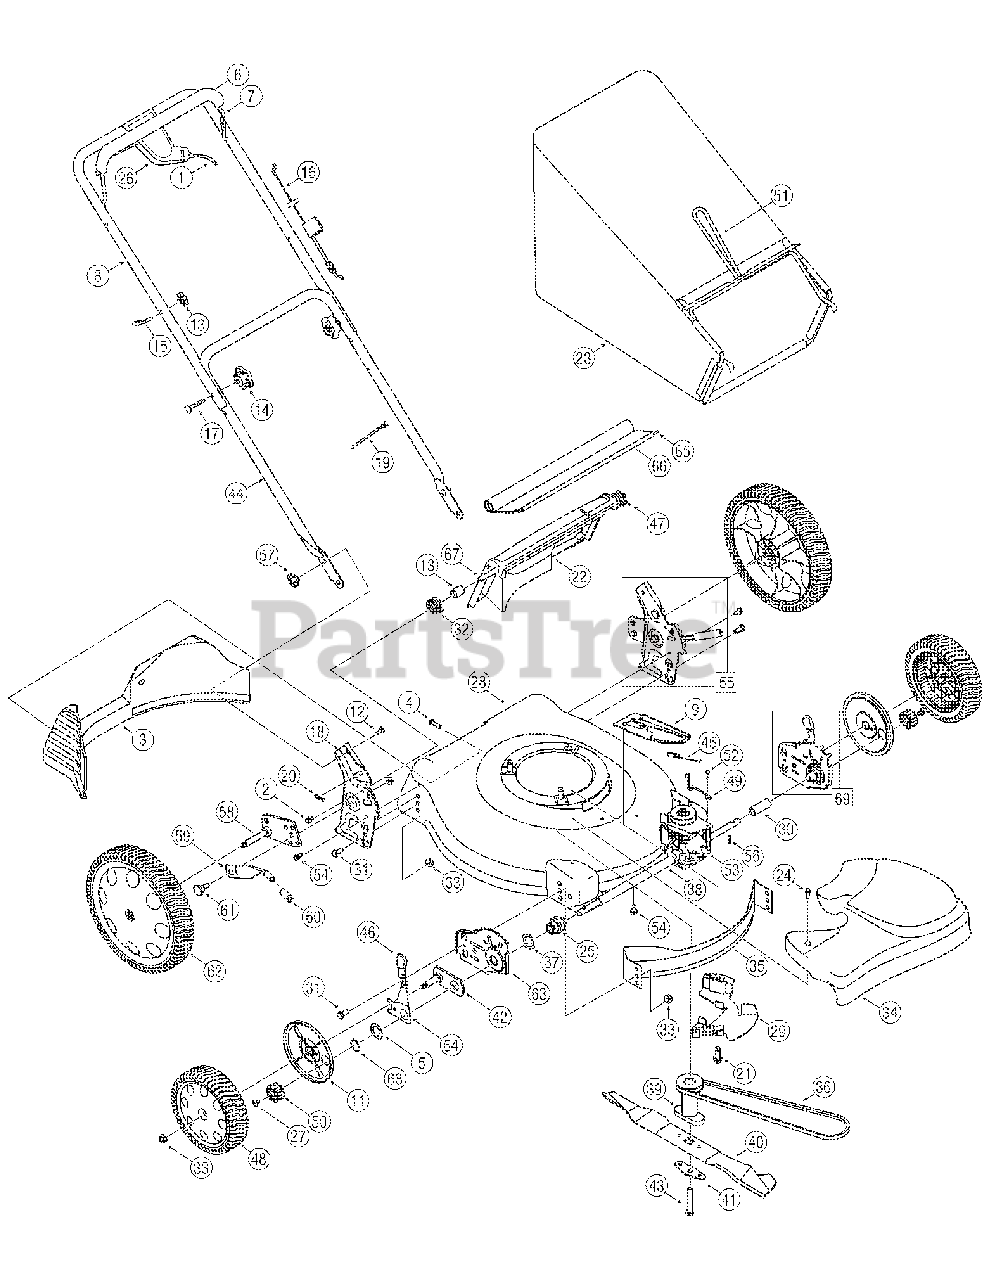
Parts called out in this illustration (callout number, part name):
1	Variable Speed Cable
2	TT Screw 1/4-20 x 0.5
3	Rear Baffle 21" Rd.
4	Screw 1/4-15
5	Flat Washer
6	Deluxe Bail Cover
10	Cable Mounting Cap
11	Wheel Dust Cap
12	Carriage Bolt 1/4-20
13	Spacer.375 x.50 x 1.02" Lg.
14	Star Knob
16	Control Cable - 37.25"
17	Carriage Bolt 5/16-18 x 2.0
18	Handle Bracket - RH
18	Handle Bracket - LH
19	Cable Tie
20	Cotter Pin
21	Self-Tapping Sems Screw
22	Rear Discharge Door
23	Grassbag Assembly
24	Shoulder Screw # 12 -24
25	Front Bearing Assembly
26	Speed Control Assembly
27	Screw 1/4-20 x .390
29	Belt Keeper Bracket
30	Slev. Spacer 1.8" Lg.
31	Hex Screw, 3/8-16 x.75
32	Torsion Spring - RH
33	Flange Lock Nut, 3/8-16
34	Transmission Cover (Black)
35	Front Baffle
36	V-Belt
37	Wave Washer
38	Sleeve Spacer 9.10" Lg.
39	Blade Adapter w/ Pulley
40	21" Mulching Blade
41	Blade Bell Support
42	Pivot Plate Assembly
43	Hex Screw 3/8-24 x 2.50
45	Extension Spring
46	Adjustment Knob
47	Torsion Spring - LH
48	Front Wheel 8 x 2.125
49	Belt Keeper Wire
50	Gear 14T RH FWD
50	Gear 14T LH FWD
52	Torx Screw
53	Transmission Assembly
54	TT Scr. w/Washer 1/4-20 x.625
55	Handle Bracket Assembly - LH
55	Handle Bracket Assembly - RH
56	Dowel Pin
57	Wing Nut
58	Pivot Arm Assembly - RH
58	Pivot Arm Assembly - LH
59	Rear Spring Lever
60	Foam Grip
61	Shoulder Scr.500 Dia. x.434
62	Rear Wheel, 12 x 2.125
63	Front Height Adj. Plate - RH
63	Front Height Adj. Plate - LH
64	Front Lever - RH
64	Front Lever - LH
65	Wire
66	Rear Trailing Shield
67	Pivot Rod
68	Snap Ring
69	Height Adj. Assembly - LH
69	Height Adj. Assembly - RH
